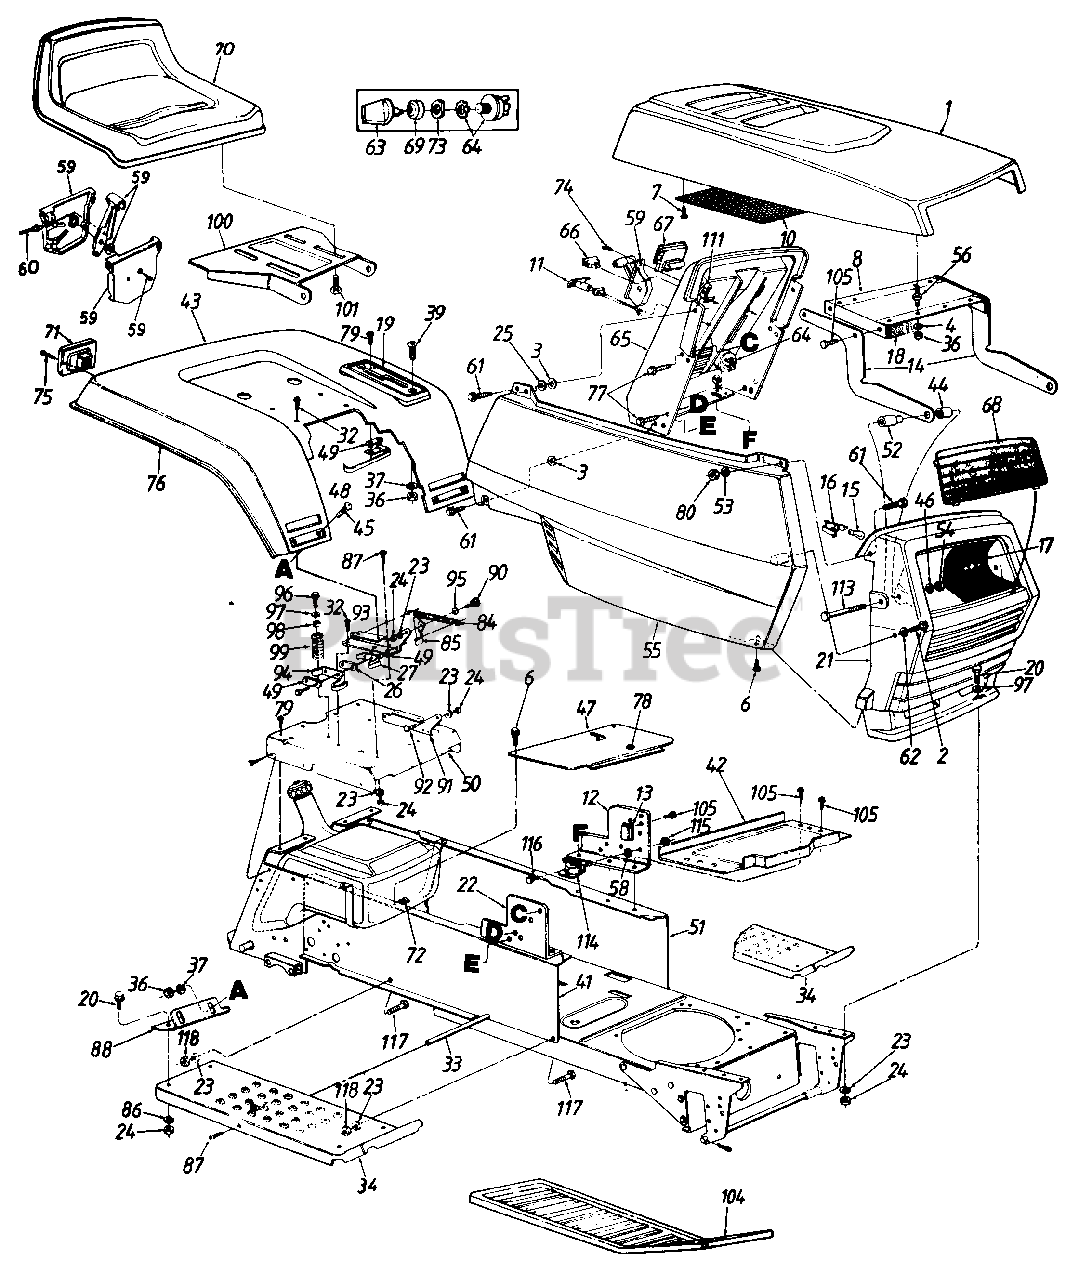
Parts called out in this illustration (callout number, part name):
3	Bolt Retainer 1/4" I.D.
4	Bell-Wash. .265" I.D. x .75"
6	Truss Mach. B-Tap Scr. #10 x .5" Lg.
7	Hex Wash Hd. AB-Tap Scr. #8 x 5" Lg.
8	Hood Plate
11	Choke Control
12	Dash Support Brkt.-L.H.
13	Circuit Breaker
14	Hood Hinge
15	Lamp
16	Twist Lock-Lamp Socket
17	Reflector-Headlight
19	Speed Control Index Brkt.
20	Hex Bolt 5/16-18 x 1.0" Lg.
21	Grille
22	Dash Support Bracket-R.H.
23	L-Wash. 5/16" I.D.
24	Hex Nut 5/16-18 Thd.
25	Fl-Wash. 1/4 I.D. x.93" O.D.
26	Insulator Center Plate
27	Seat Spring Switch
32	Hex Wash. Hd. AB-Tap Scr. 5/16 x .75" Lg.
33	Running Board Rod
37	L-Wash. 1/4 I.D.
39	Truss Mach. Scr. 1/4-20 x 1.0" Lg.
41	R.H. Side Frame
42	Battery Plate
45	Carriage Bolt 1/4-20 x .50" Lg.
46	Fl-Wash. .328" I.D. x .68" O.D.
47	Transmission Panel
48	Reverse Safety Switch
49	Insulator End Plate
50	Seat Plate
51	L.H. Side Frame
52	Shld. Spacer ,33" l.D.
53	Fl-Wash. .281" I.D. x .5" O.D.
54	Hex Cent. L-Nut 5/16-18 Thd.
55	Side Cover-R.H.
56	Double Ended Stud 1/4-20 Thd.
58	Ext. L-Wash. 1/4" I.D.
59	Throttle Control Box Ass'y.
60	Throttle Control Wire 35" Lg.
61	Hex Bolt 1/4-20 x .62" Lg.
62	Fl-Wash. .281" l.D. x .73" O.D.
64	Ignition Switch
66	Light Switch
67	Ammeter
68	Lens
69	Ignition Switch Cap
71	Taillight Ass'y.
72	Speed Nut #10Z
73	Ignition Switch Nut
74	Truss Mach. AB-Tap Scr. #10 x .5" Lg.
75	Truss Hd. AB-Tap Scr. #6 x .62" Lg.
76	Trim Strip-81n
77	Hex Wash. Hd. Tap Scr. 1/4 x .75" Lg.
78	Snap Bushing
79	Hex Wash. Hd. AB-Tap Scr. #8 x 50" Lg.
80	Hex L-Nut 1/4-20 Thd.
84	Ext. Spring 5.31" Lg.
85	Seat Lift Brkt.
86	Bell-Wash. .345" l.D. x .88" O.D.
87	Truss Machine Scr. 5/16-18 x 7Sn Lg
95	Spr.-Wash. .445" l.D.
96	Hex Wash. Hd. Tap Scr. 5/16-18 x .751' Lg.
97	Fl-Wash..344" l.D.
99	Compression Spring
100	Seat Pivot Bracket
101	Hex Tap Scr. 3/8-16 x .75"
105	Hex Tap Scr. 1/4-20 x .5" Lg.
111	Speed Nut 1/4-20 Thd.
113	Hex Bolt 5/16-18 x 2.75n
114	Solenoid
115	Hex Sems Nut 1/4-20 Thd.
116	Hex Bolt 1/4-20 x .5" Lg.
117	Rib Neck Bolt 5/16-24 x .75
118	Hex Nut 5/16-24 Thd.
